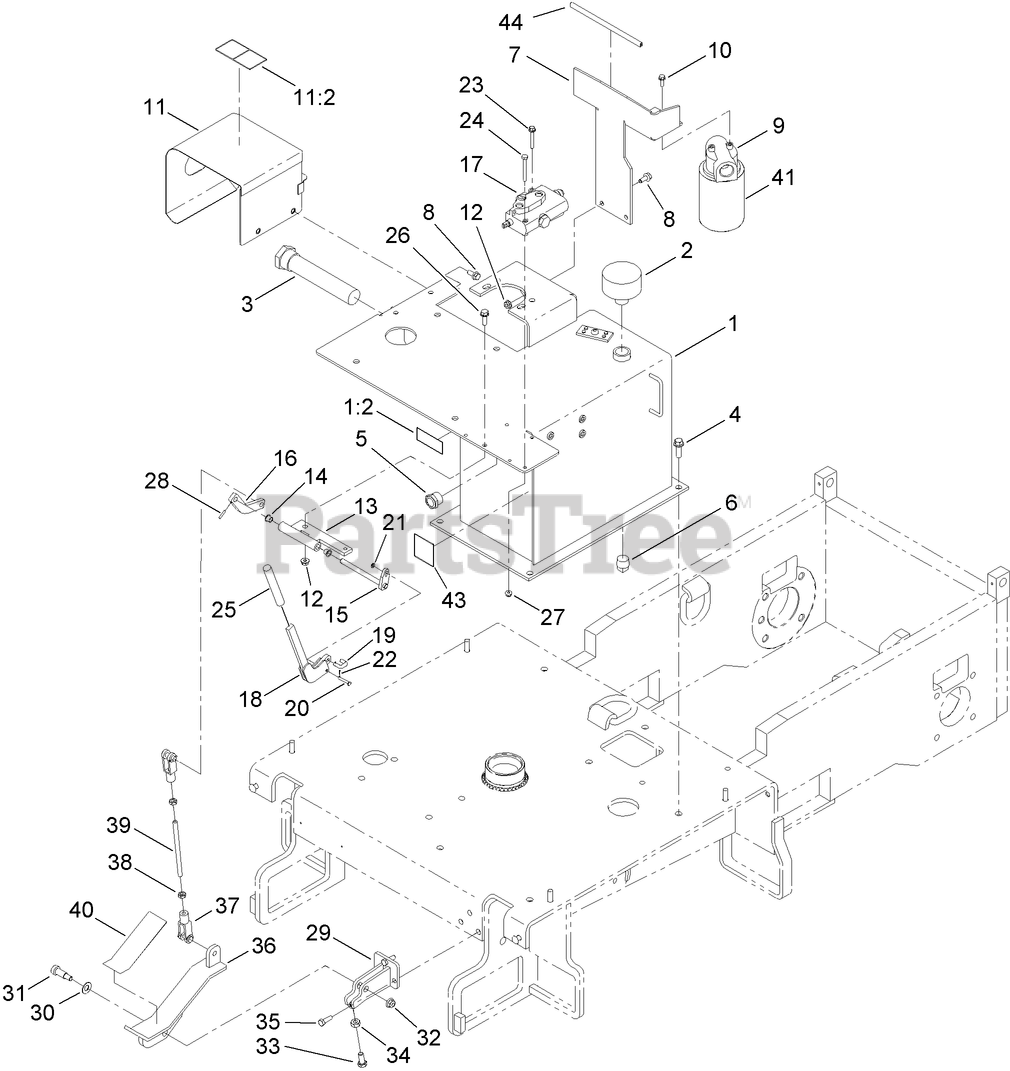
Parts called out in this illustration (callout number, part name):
1	HYD TANK ASM
1:2	DECAL-CAUTION, HYD FLUID
2	BREATHER-FILLER
3	STRAINER
4	SCREW-HHF
5	GLASS SIGHT ASM
7	BRACKET-FILTER, OIL
8	SCREW-HHF
9	FILTER-RETURN
10	SCREW-HHF
11	HEAT SHEILD ASM
11:2	DECAL-SURFACE, HOT
12	NUT-FLANGE
13	GUIDE-SHAFT
14	BEARING
15	LEVER-CONTROL, FOOT VALVE
16	ACTUATOR-ARM
17	DIRECTIONAL HYD VALVE ASM
18	LEVER-VALVE, CONTROL
19	LINK-HANDLE, VALVE
20	PIN-CLEVIS
21	WASHER
22	PIN-COTTER
23	SCREW-HHF
24	SCREW-HH
25	GRIP-HANDLE
26	SCREW-HHF
27	NUT-HF
29	MOUNT-PEDAL
30	WASHER-BELLEVILLE
31	SCREW-HSBH
32	NUT-HF, NI
33	SCREW-HH
34	NUT-HEX
35	SCREW-HH
36	PEDAL-DUMP
37	END-YOKE
38	NUT-HJ
39	ROD-LINKAGE
40	TREAD-SKID
41	ELEMENT-HYD OIL, 10 MICRON
43	DECAL-P BRAKE
44	TRIM-FILTER BRACKET
